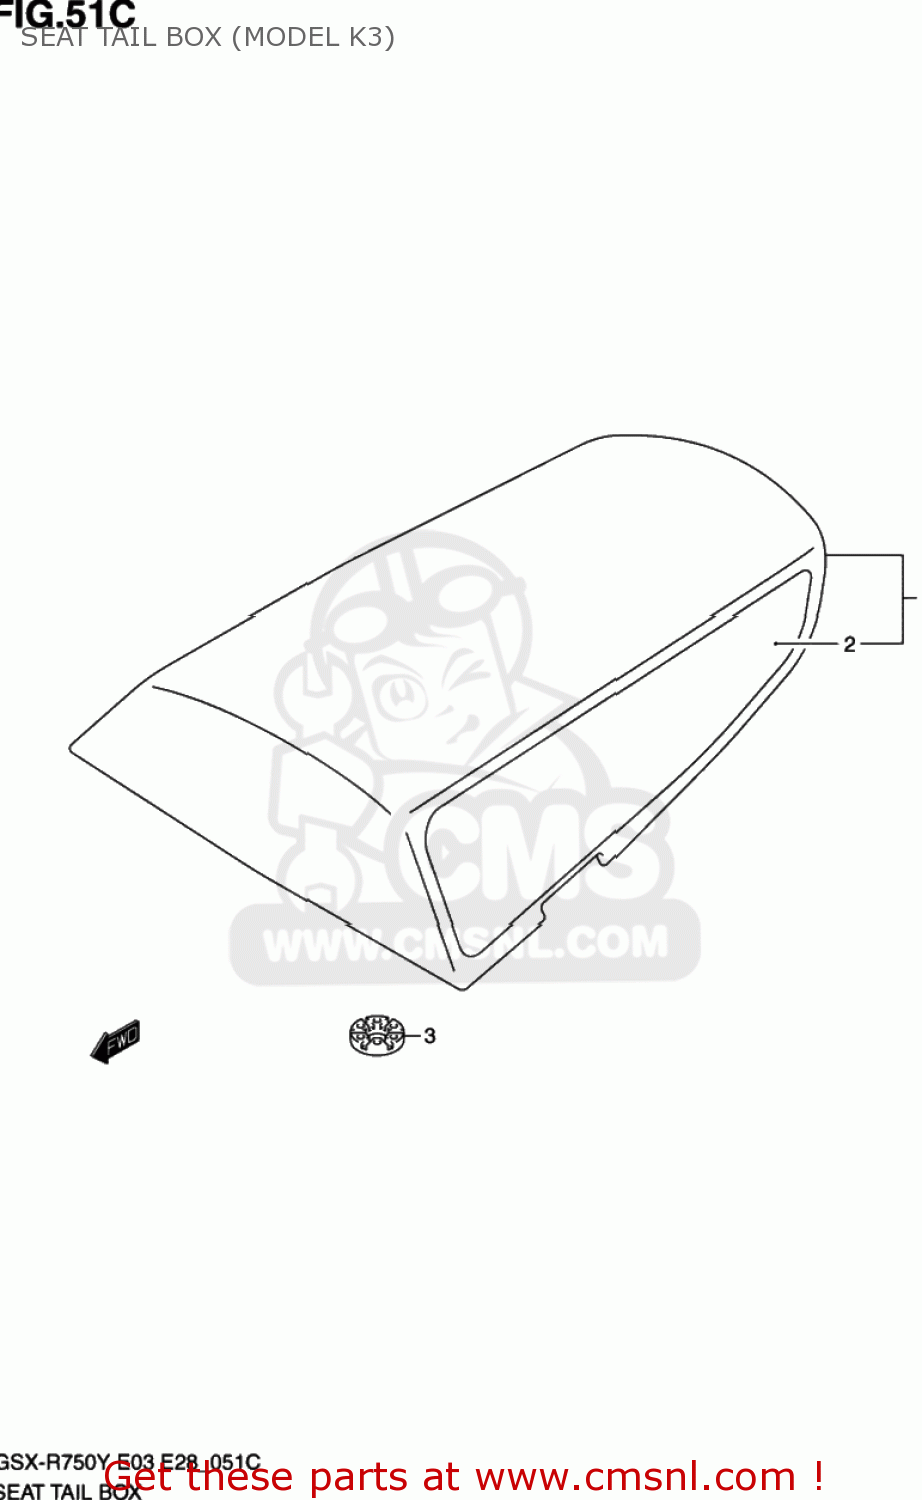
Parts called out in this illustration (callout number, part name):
1	BOX ASSY,SEAT TAIL(BLACK)
2	TAPE SET,BOX
3	CUSHION
